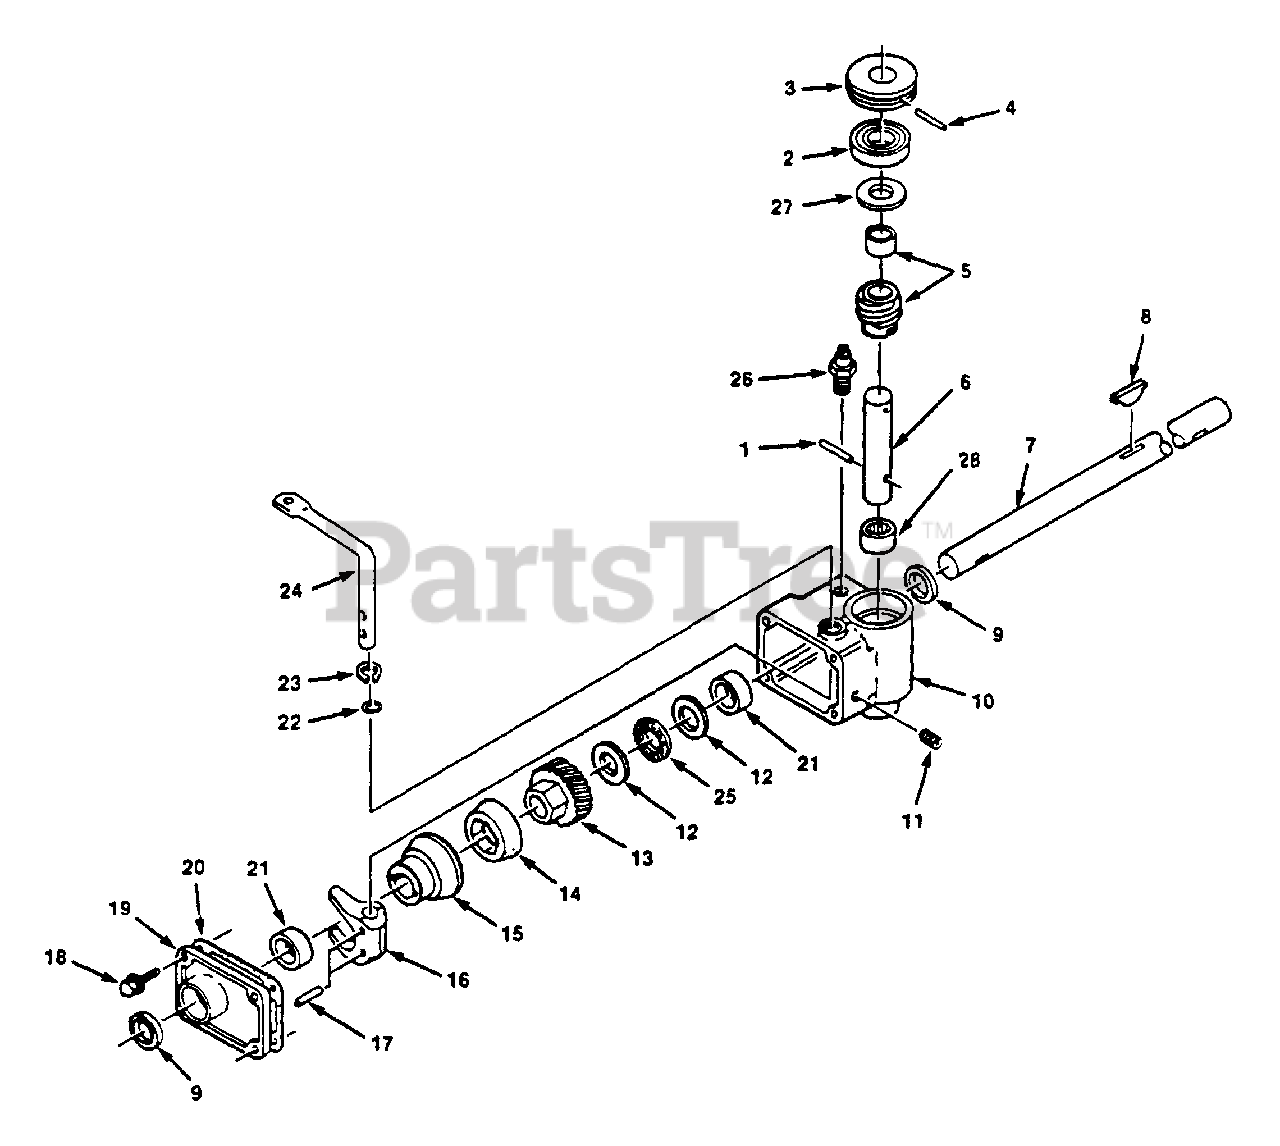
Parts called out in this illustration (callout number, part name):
1	PIN
2	BEARING, BALL
3	PULLEY
4	PIN
5	WORM 4 SPACER
6	SHAFT, WORM
7	DRIVESHAFT
8	KEY - 1/8 X 1/2"
9	SEAL
10	GEAR REDUCER HOUSING ASSY
11	PLUG - PIPE
12	RACE - Bearing
13	GEAR - WORM
14	CONE - Friction
15	DRUM, CLUTCH
16	FORK-Shift
17	PIN
18	SCREW - 1/4-20 X 7/8"
19	COVER-Gearbox
20	GASKET
21	BUSHING
22	O-RING
23	RING, RETAINING
24	LEVER, SHIFT
25	BEARING - THRUST
26	VENT
27	WASHER
28	BEARING, NEEDLE
